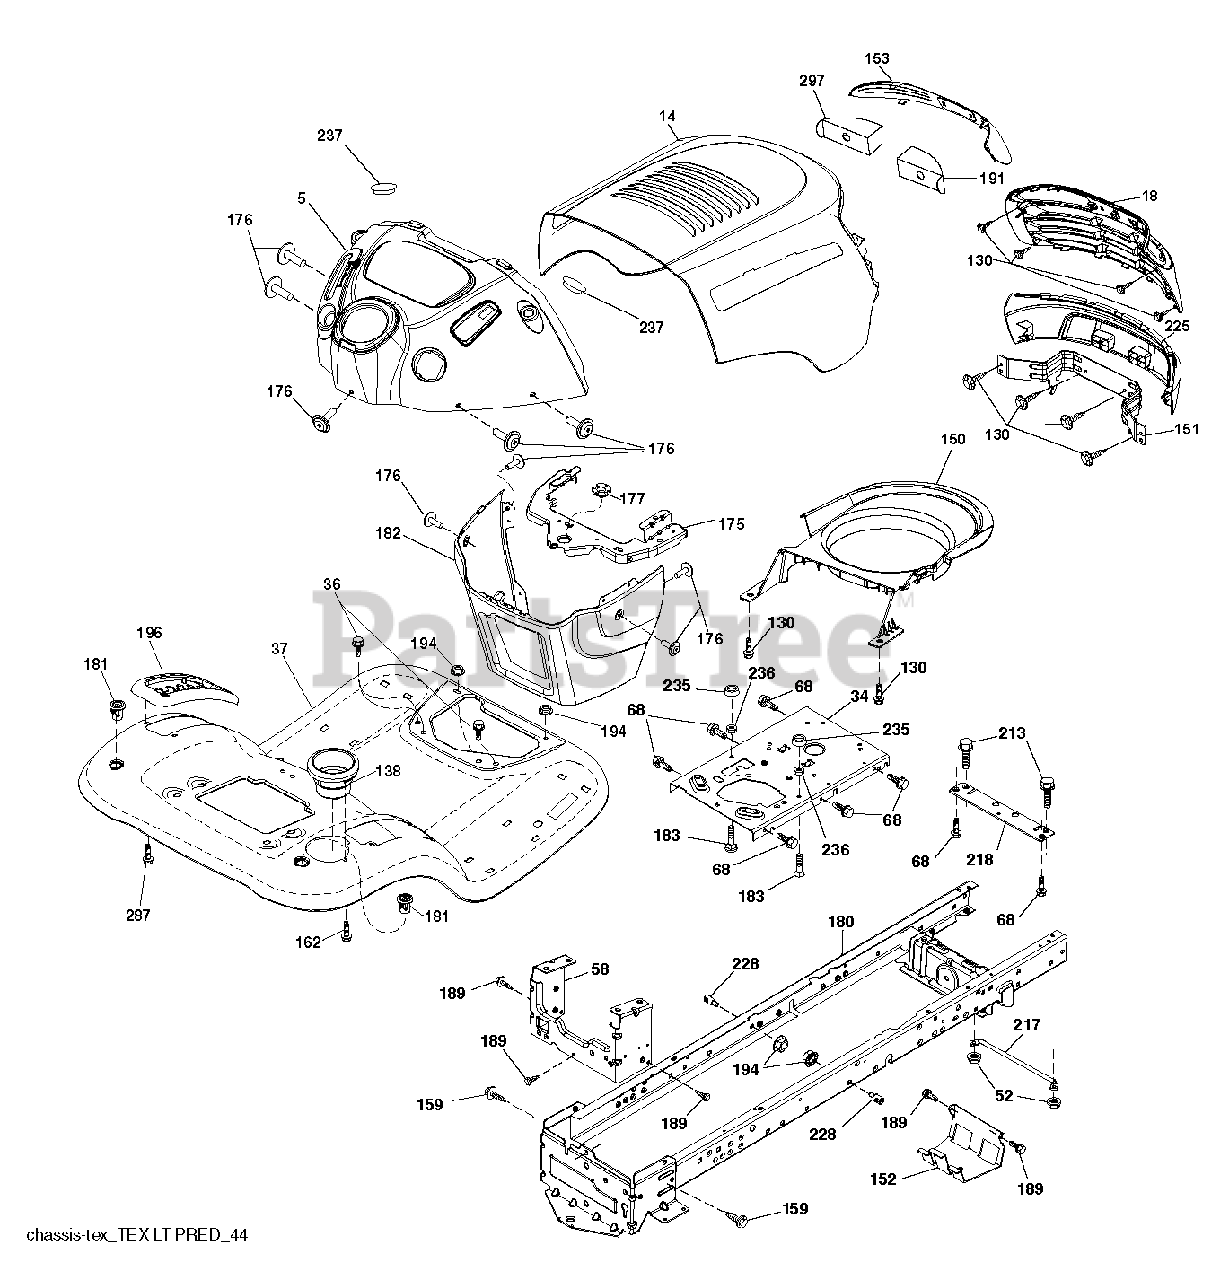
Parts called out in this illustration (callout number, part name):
58	DRAWBAR UPPER
68	SCREW LT
130	SCREW.#10 X 0.750.BOS THREAD
138	CUPHOLDER
152	SHIELD BROWNING
159	SCREW, 3/8-16X3/4
162	SCREW,HEX
176	SCREW.#10-24X5/8.RN.QU
180	CHASS.WLDMNT.TL.12GA/2P.48/54
181	FEND/FTRST.PCH.CPH.NFW
183	BOLT.5/16-18X1-1/4 FULL THD
189	SCREW
194	NUT LOCK HEX FLANGE 5/16-18
196	CONSOLE ASM. DECK LIFT
228	STUD.FASTNER.W/D.ANTI-
235	SPACER FENDER
236	JAM LOCK NUT
